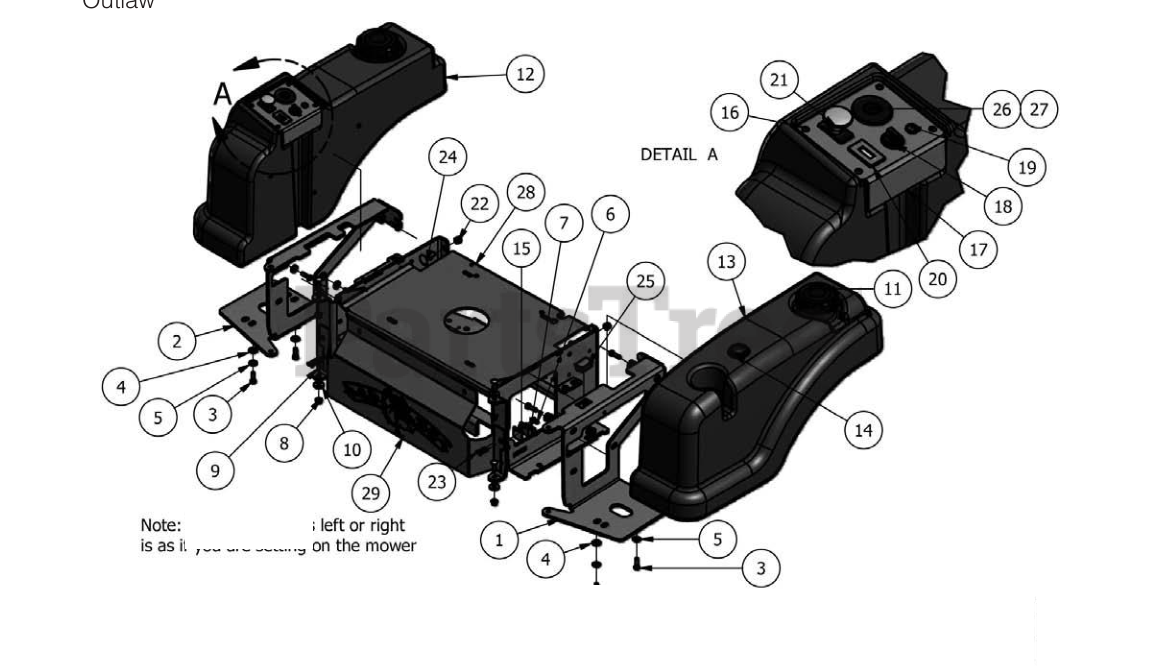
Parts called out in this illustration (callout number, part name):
1	Tank Support-Right
2	Tank Support-Left
3	5/16-18 x 1 Grade 5 Hex bolt Zinc
4	5/16 USS Flat Washer Zinc
5	5/16 Lock Washer Zinc
6	10-24 Nylon Insert Locknut Zinc Orange Nylon
7	Drive Arm Safety Switch
8	5/16-18 Nylon Insert Flange Nut Zinc Orange Nylon
9	5/16-18 x 1 Carriage Bolts Zinc
10	.360ID Plastic Washer
12	Right Tank
14	Fuel Gauge and Grommet
15	Switch Block Plastic
16	10-32 x 3/8 Button Socket C/S 18-8 SS
17	Control Panel
18	12V AUX Connection
20	Tachometer
21	PTO Engager
22	3/8-18 Nylon Insert Locknut Zinc Orange Nylon
23	10-24 x 1 Button Socket C/S 18-8 SS
24	3/8" x 1-1/4" Carriage Bolt
25	Control Panel Stop
26	Ignition Switch
27	Ignition Key
28	Seat Plate
29	Cooler Cover
